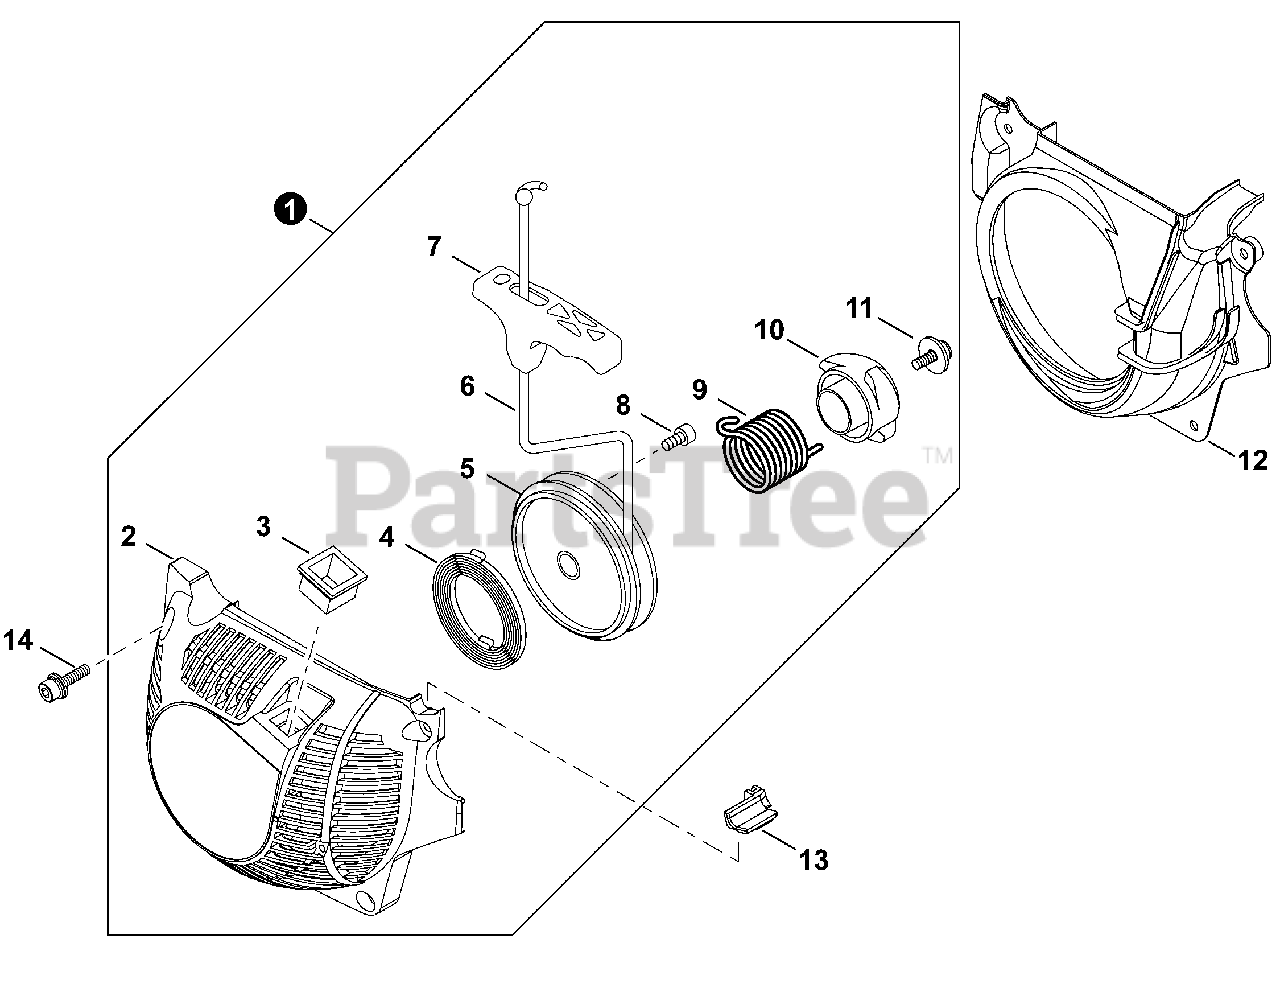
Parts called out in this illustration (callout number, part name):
1	STARTER ASSY
2	CASE, STARTER
3	GUIDE, ROPE
4	SPRING, RECOIL
5	REEL, ROPE
6	ROPE, STARTER Ø3.8×750
7	GRIP, STARTER
8	BOLT 4×10
9	SPRING, TORSION
10	PAWL CATCHER
11	SCREW 5
12	COVER, FAN
13	GROMMET, NEEDLE
14	BOLT M4×16
